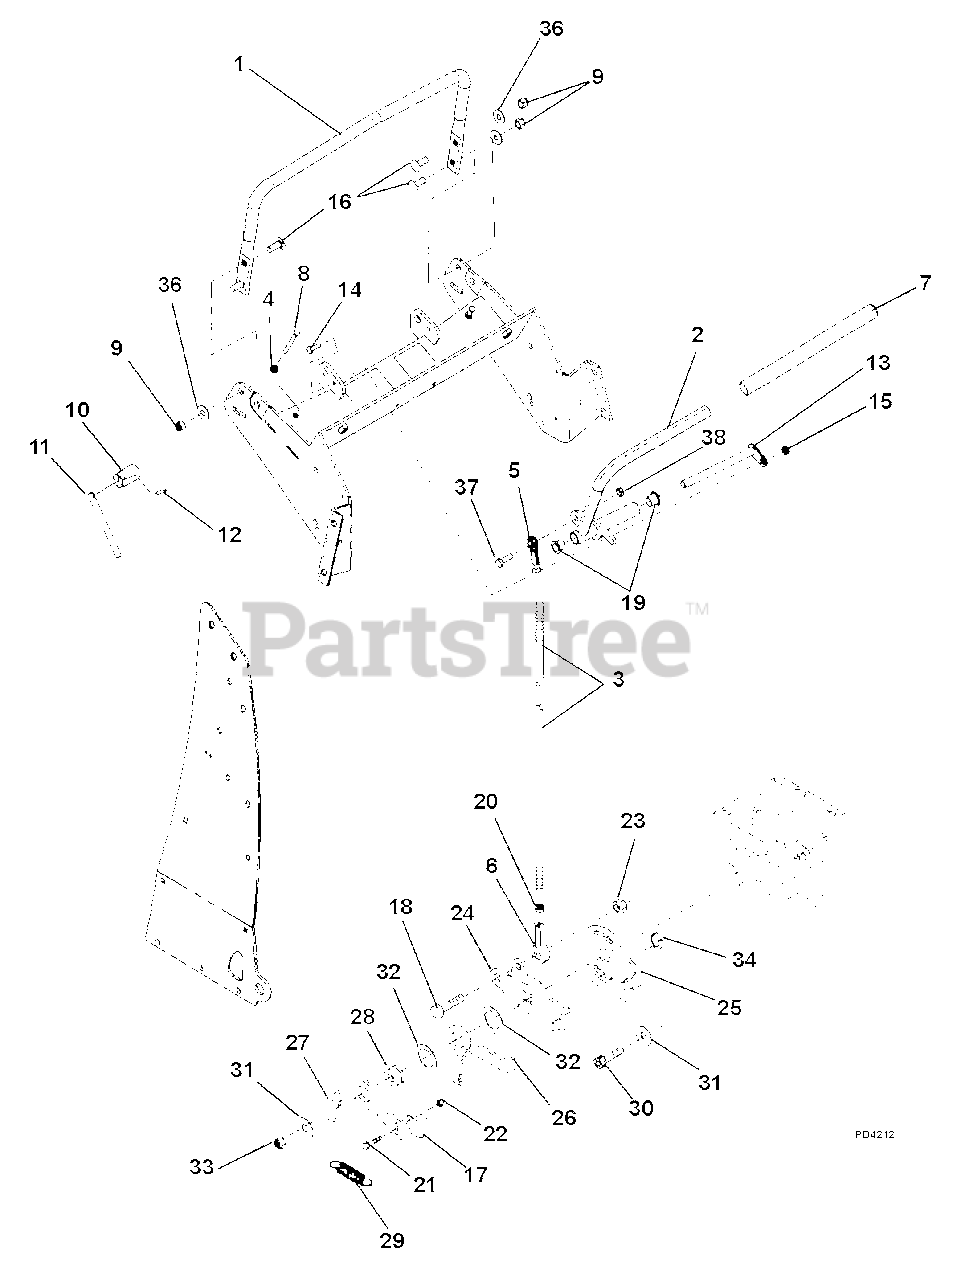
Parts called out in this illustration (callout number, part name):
1	Support, Handle
2	LH Control Lever w/ Grip
3	Control Rod
4	Flange Nut, M16 x 1.0
5	Alignaball, 5/16 LH Thread
6	Alignaball, 5/16 RH Thread
7	Grip, Control
8	Cap Screw, Reverse Stop M6 x 1
9	Nut, Lock, Nylon M10-1.5
10	Base, Lock Lever
11	Lever, Lock
12	Pin, Spring 5/32 x 1
13	Weldment, Pin and Lock
14	Bolt, Hex .25-20 x .75
15	Nut-Locking-Nylon .250-20
16	Bolt, Hex M10 x 1.5 x 25
17	Switch, Plunger (Double Pole) N.O.
18	Bolt, Hex .31-18 x 1.00
19	Bearing, Flange .500 x .620 x .500
20	Nut, Jam .31-24
21	Screw-Machine 10-24 x .625
22	Nut-Locking-Nylon 10-24 w/ Insert
23	Nut, Locking, Center .31-18
24	Arm, Control Return
25	Arm, Return
26	Arm, RH Inner Return
27	Arm, LH Outer Return
28	Spacer, Return
29	Spring, Extension
30	Screw, 5/16 x 1 Patch Lock
31	Washer
32	Washer, Nylon
33	Nut, Center Lock .31-24
35	Washer, Flat, Steel .406 x .812 x .065
36	Washer, Flat, Steel .438 x 1.00 x .083
37	Bolt, Hex .25-20 x .75
38	Nut, Locking, Nylon .312-18
